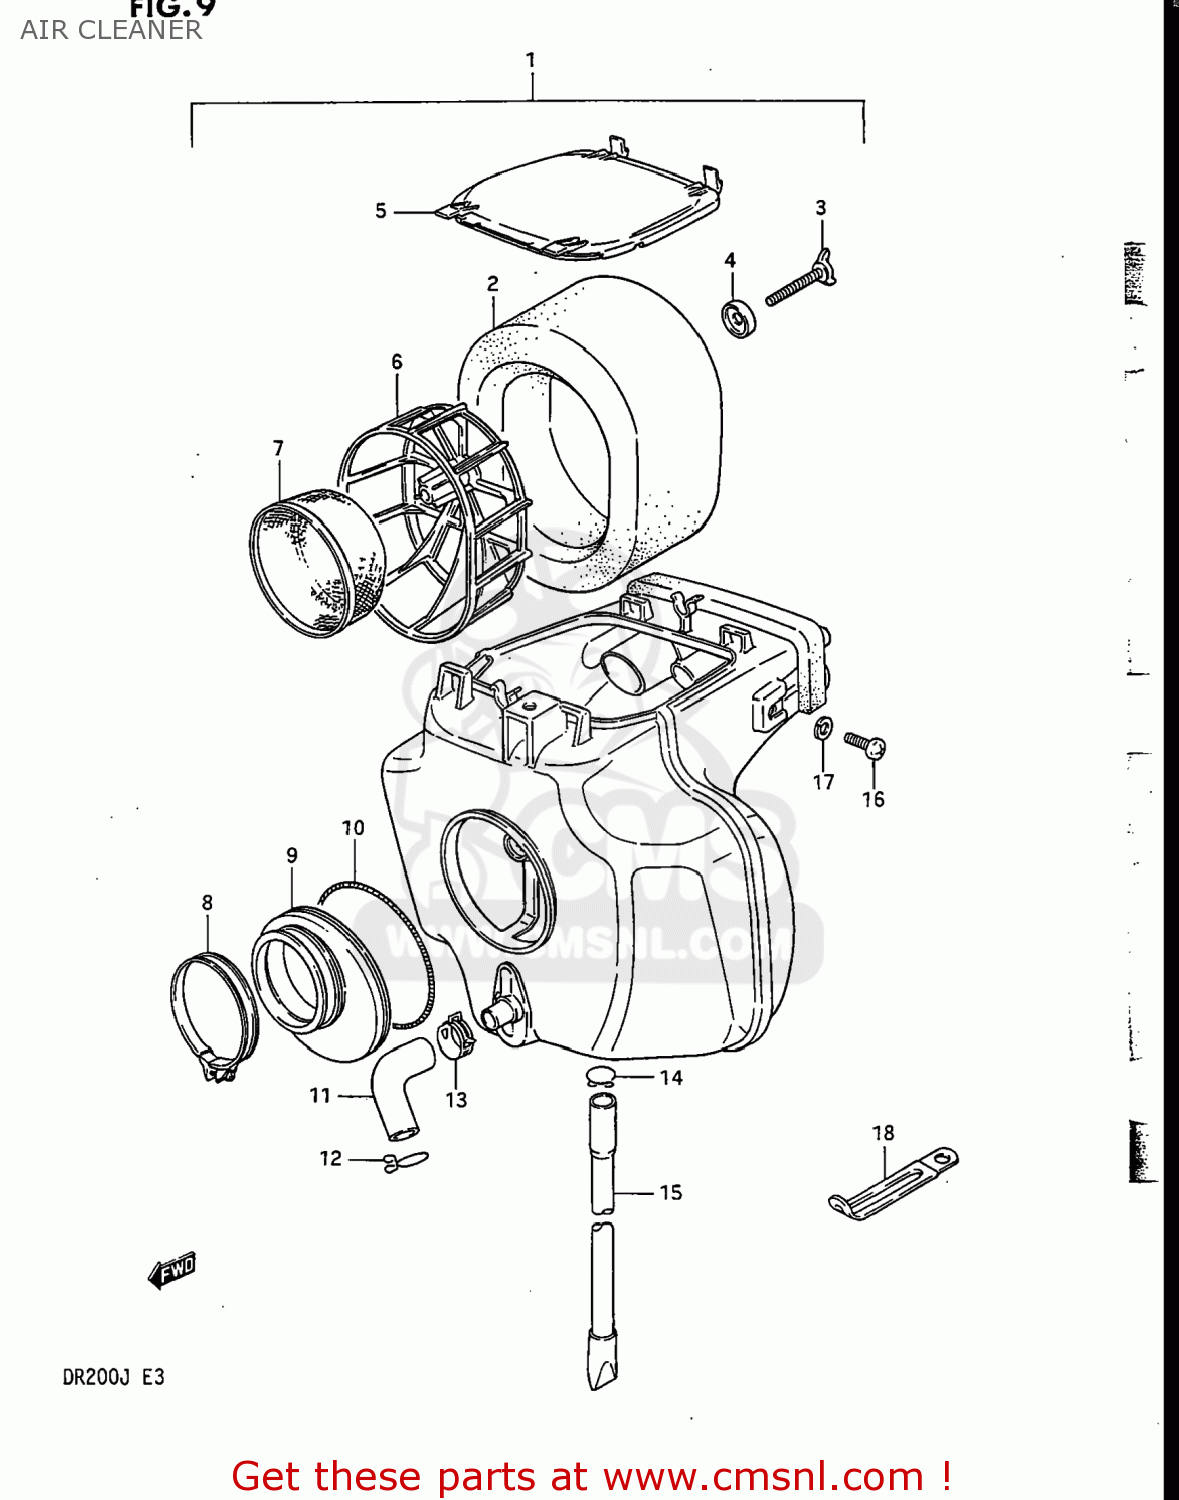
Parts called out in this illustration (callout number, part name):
1	CLEANER ASSEMBLY,AIR
2	FILTER,AIR CLEANER
3	BOLT,WING
4	WASHER,FILTER HOLDER
5	CAP
6	HOLDER,FILTER
7	TRAP
8	CLAMP
9	TUBE,AIR CLEANER OUTLET
10	CLAMP,AIR CLEANER SIDE
11	TUBE,BREATHER
12	CLIP,BREATHER TUBE
13	CLIP
14	CLIP
15	DRAIN TUBE
16	SCREW
17	WASHER,LOCK
18	CLAMP
